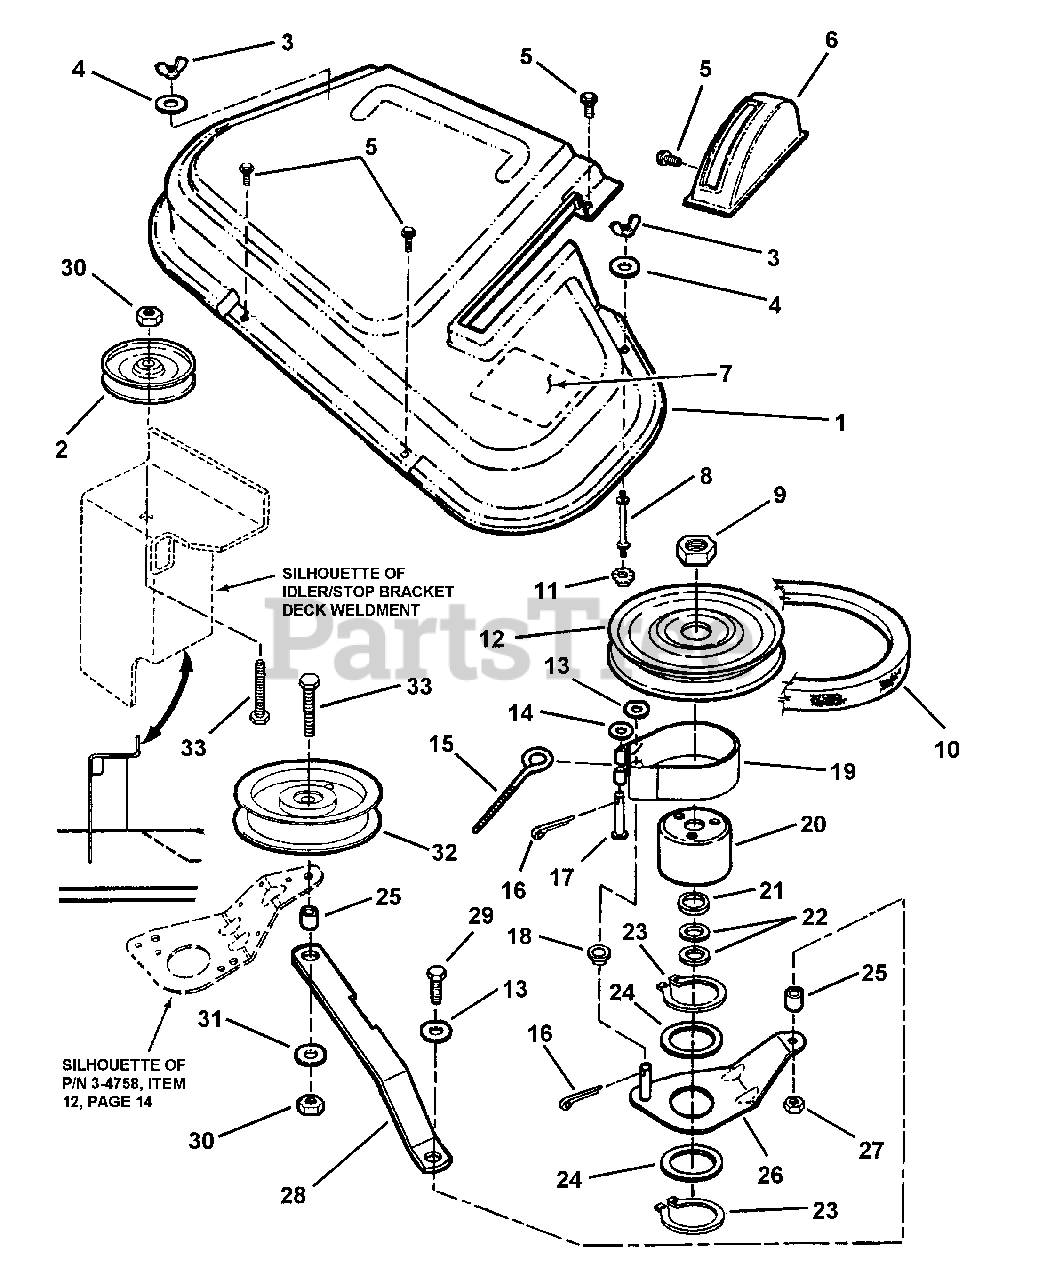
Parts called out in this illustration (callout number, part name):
1	COVER, Spindle 42"
2	PULLEY, Seam Welded Idler
3	WINGNUT, 5/16-18
4	WASHER, 11/32" x 11/16" x 1/16" Flat
5	SCREW, 1/4-20 x 5/8" Hex Washer Head, Self-Tap
6	COVER, Lift Quadrant
7	DECAL, Brake Operation
8	STAND-OFF, 3-1/2"
9	NUT, 3/4-16 Hex Jam
10	BELT, (110.28", "5L" Section)
11	NUT, 3/8-16 Hex Flange Lock
12	PULLEY, 5" O.D.
13	WASHER, 3/8" Flat
14	WASHER, 1/4 Flat
15	EYE-BOLT, 5/16-18 x 3"
16	COTTER PIN, 3/32 x 3/4"
17	PIN, 1/4 x 1-5/8" Clevis
18	SPACER
19	ASSEMBLY, Brake Band
20	DRUM, Brake
21	SPACER, 3/4" I.D.
22	WASHER, 3/4" Flat
23	RING, 2" External Retaining
24	WASHER, 2" I.D., Nylon
25	SPACER
26	WELDMENT, Brake Arm
27	NUT, 3/8-24 Hex Center Lock
29	SCREW, 3/8-24 x 1" Hex Head Cap Grade 5
30	NUT, 3/8-16 Hex Nyloc
31	WASHER, 3/8" Flat
32	PULLEY, 4-1/8" Flat Idler
33	SCREW, 3/8-16 x 1-1/2" Hex Head Cap Grade 5
